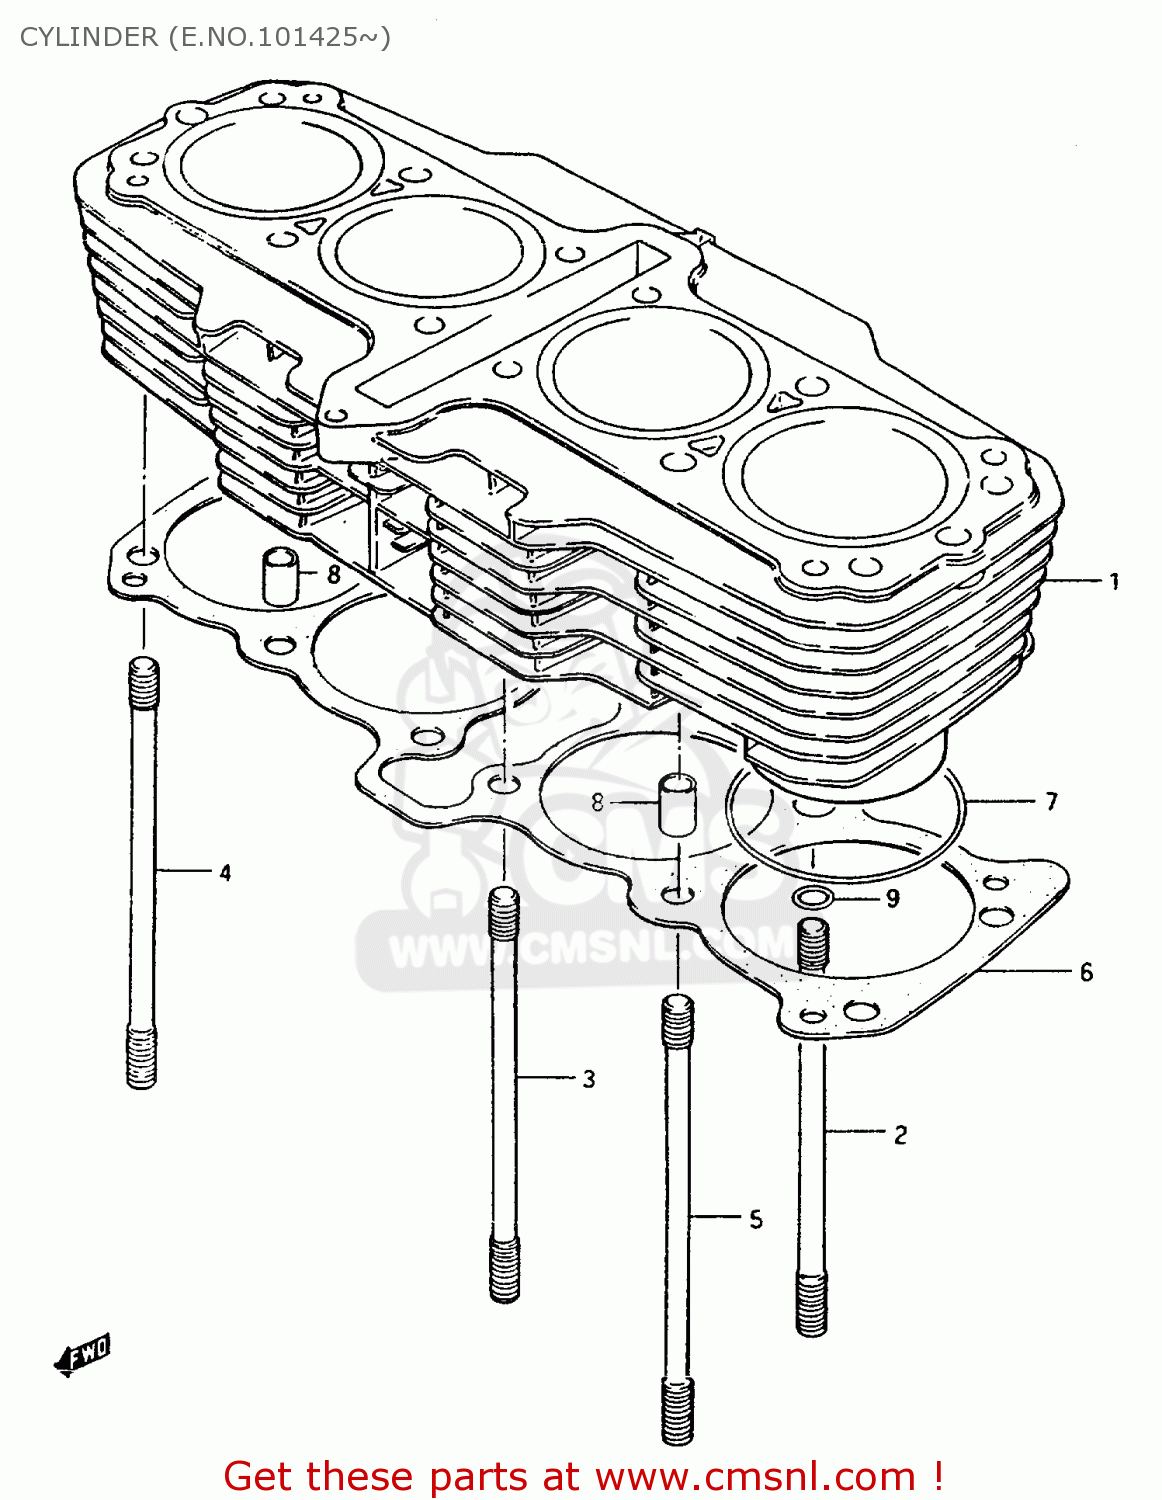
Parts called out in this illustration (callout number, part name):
1	CYLINDER
2	STUD
3	BOLT,STUD
4	STUD
5	BOLT,STUD
6	GASKET,CYLINDER HEAD (NAS)
7	O RING(D:2,ID:77)
8	PIN
9	O RING(D:2.4,ID:11)
